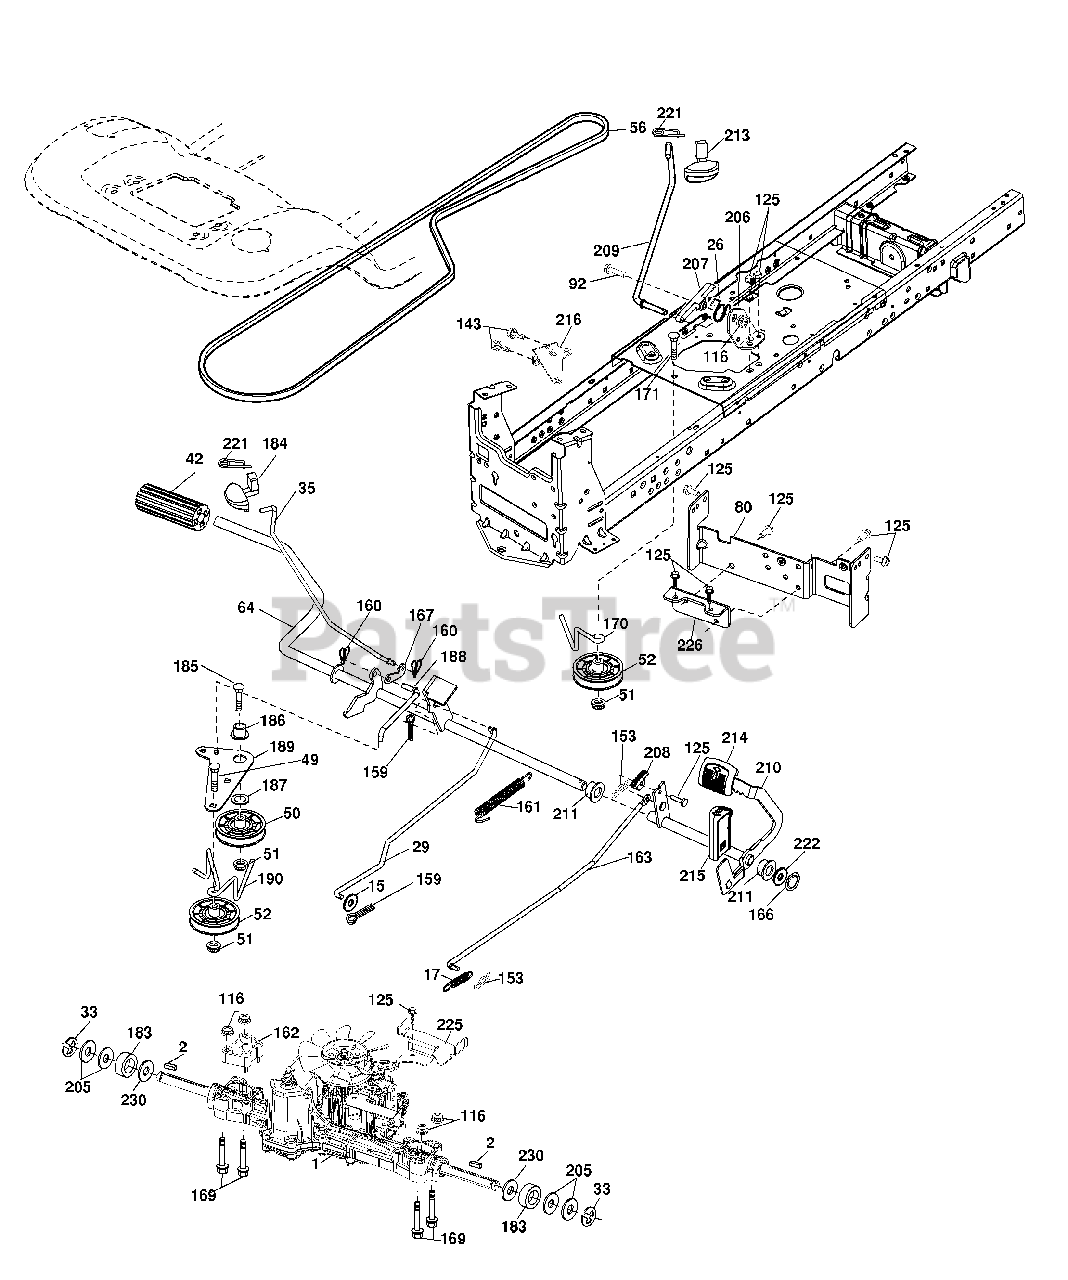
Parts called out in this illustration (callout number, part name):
1	Transaxle, TUFFTORQ K46
2	Key Square
15	Washer 13/32 x 13/16 x 16 Ga.
17	Spring, Brake
26	Spring Return Cruise
29	Rod, Brake
35	Rod, Brake, Park
42	Cover, Foot Pedal
50	Pulley Idler Flat
51	Lock Nut 3/8-16
52	Idler V-Groove 910" Offset
56	V-Belt, Drive
64	Shaft Asm. Pedal Brake Control
80	Strap Torque
92	Bolt Fin Hex 5/16-18 unc x 1.25
116	Nut Lock Hex Flange 5/16-18
125	Screw 5/16-18 x 3/4
143	Screw 5/16-18 x 1/2
153	Retainer Spring
159	Pin Cotter 1/8 x 3/4
160	Retainer Clip
161	Spring, Return, Clutch
162	Spacer Transaxle
163	Rod Pedal Control
166	Nut Push
167	Latch Brake Parking
169	Bolt Hex 5/16-18 x 3.75
170	Keeper Belt Centerspan
183	Spacer Axle
184	Handle Parking Brake
186	Spacer Retainer
187	Washer
188	Link Clutch Ground Drive
189	Bellcrank Ground Drive
190	Keeper Bellcrank Ground Drive
205	Washer 25/32 x 1-5/8 16 Ga.
206	Bracket Mount Latch Cruise
207	Latch Control Cruise
208	Gear Sector Control Cruise
209	Rod Control Cruise
210	Rockr Asm. Pedal Control
211	Bearing Nylon
213	Knob control Cruise
214	Pad Pedal Forward
215	Pad Pedal Reverse
216	Bracket Pulley Idler
221	Retainer Spring Clip
222	Washer 21/32 x 1-1/4 10 Ga.
225	Keeper Bolt Transaxle
226	Bracket Mount Torque
230	Washer Hardened
